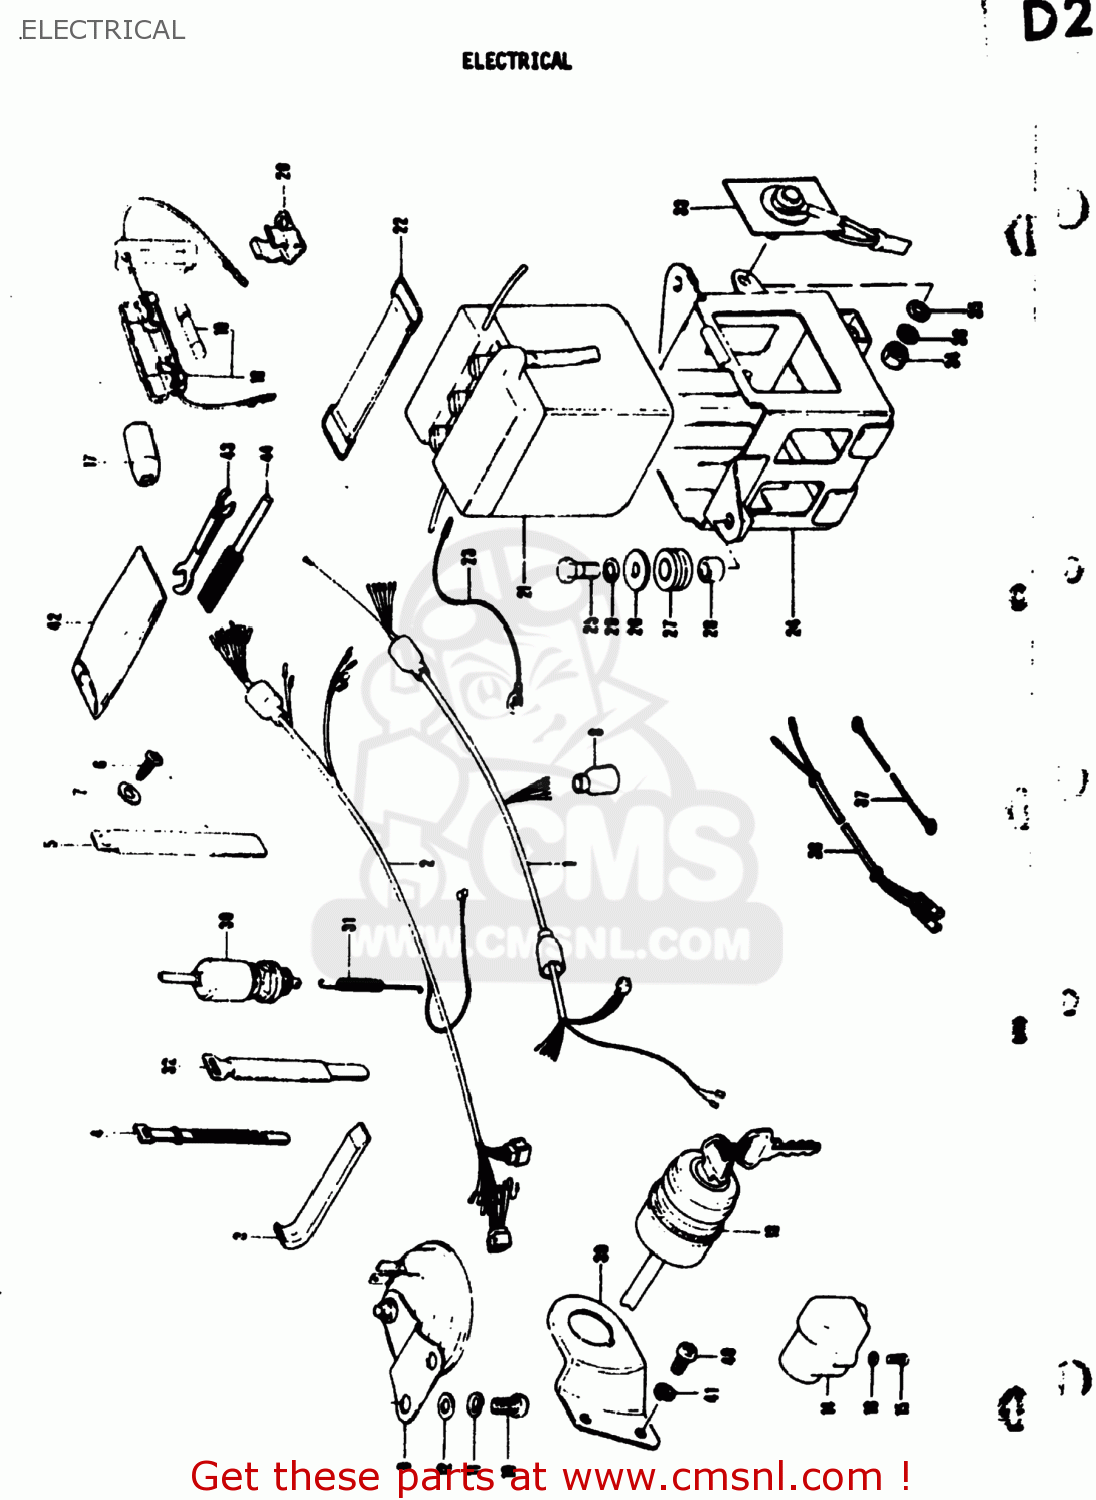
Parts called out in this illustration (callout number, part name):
1	HARNESS,WIRING
2	HARNESS,WIRING
3	BAND
4	CLAMP
5	CLAMP
7	WASHER
8	COVER,WIRING HARNESS
9	HORN ASSEMBLY
10	SCREW
11	LOCK WASHER
12	WASHER
13	SWITCH ASSEMBLY,IGNITION
14	LOCK ASSY,STEERING
15	Screw
16	LOCK WASHER
17	SEAL,DUST(10X17X45)
18	BOX ASSEMBLY,FUSE
19	FUSE(15A)
20	HOLDER,FUSE CASE
21	BATTERY ASSY(6N4-2A4.2AH)
22	BAND
23	LEAD WIRE
24	HOLDER,BATTERY
25	BOLT
26	WASHER (6.5X20X1.2)
27	CUSHION
28	SPACER (7X9X7)
29	LOCK WASHER
30	SWITCH,BRAKE LAMP
31	SPRING
32	CLAMP
33	RECTIFIER ASSEMBLY
34	NUT
35	WASHER
36	LOCK WASHER
37	WIRE
38	WIRE,REAR TURN SIGNAL,LEFT
39	BRACKET,IGNITION SWITCH
40	SCREW
41	LOCK WASHER
42	TOOL SET
43	WRENCH, CONTACT POINT
44	CONTACT POINT FILE
